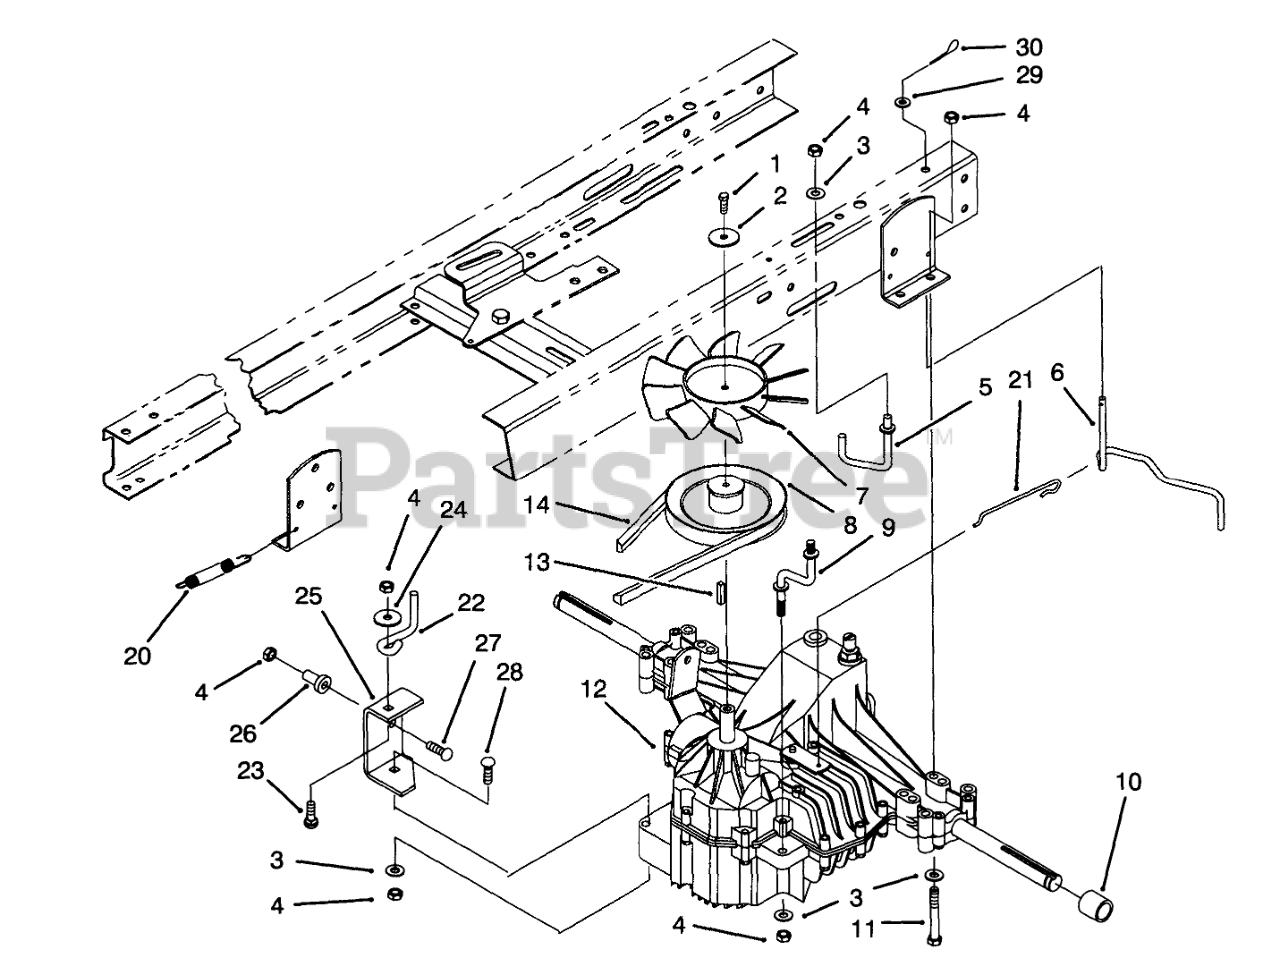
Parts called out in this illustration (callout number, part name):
1	SCREW-HH
2	WASHER-FLAT
3	WASHER-PLAIN
4	NUT-LOCK, NI
5	GUIDE-TRANS BELT, LH
6	LEVER - BYPASS
7	FAN-7"
8	HYDRO TRANS PULLEY
9	TORQUE STRAP
10	SPACER
11	SCREW-HH
12	Transaxle
13	KEY-PUMP
14	V-BELT
20	SPRING-RETURN, BRAKE
21	WIRE - BYPASS
22	TRANS BELT GUIDE
23	BOLT-CARR
24	WASHER-PIVOT
25	Bracket-Speed Control
26	BUSHING-FLANGE
27	SCREW-CARR
28	BOLT-CARR
29	WASHER-FLAT
30	PIN-COTTER
